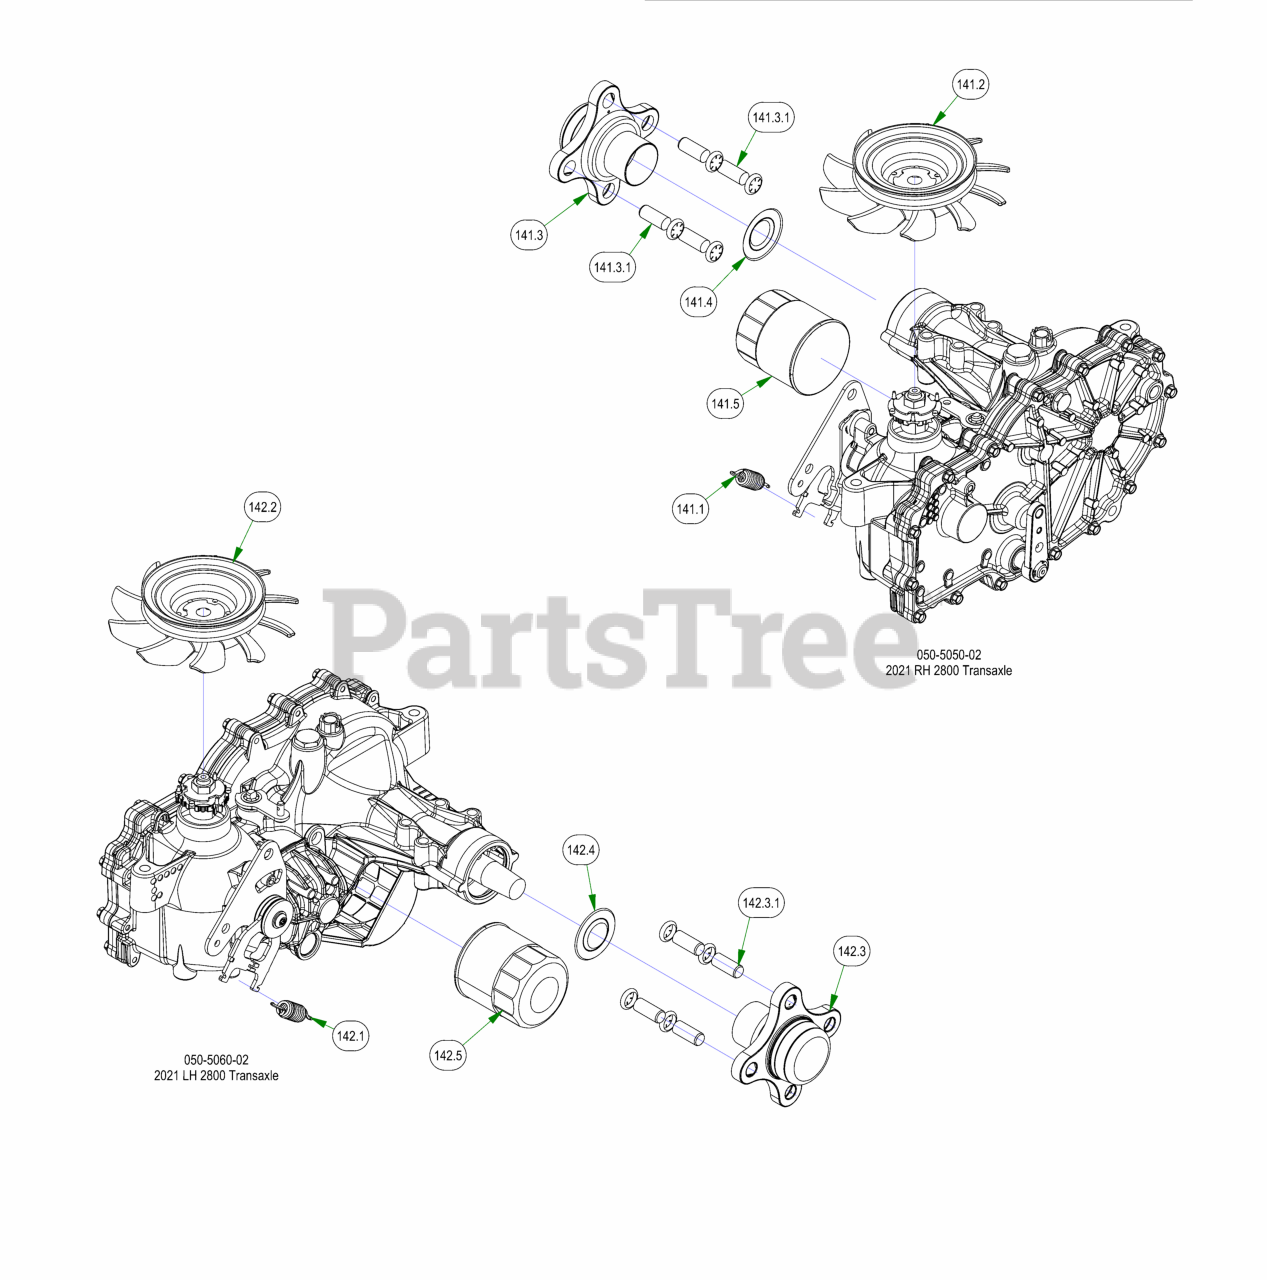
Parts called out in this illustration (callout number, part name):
141	2021 RH 2800 Transaxle
141.1	Gold Transaxle Spring
141.2	2021 ZT/Maverick Transaxle Fan/Pulley Kit
141.3	ZT Transaxle Wheel Hub
141.3.1	Transaxle Wheel Studs/ Drum Brake Studs
141.4	2021 ZT/Maverick Transaxle Seat Kit (ZT-2800)
141.5	ZT Hydraulic Filter
142	2021 LH 2800 Transaxle
142.1	Gold Transaxle Spring
142.2	2021 ZT/Maverick Transaxle Fan/Pulley Kit
142.3	ZT Transaxle Wheel Hub
142.3.1	Transaxle Wheel Studs/ Drum Brake Studs
142.4	2021 ZT/Maverick Transaxle Seal Kit (ZT-2800)
142.5	ZT Hydraulic Filter
